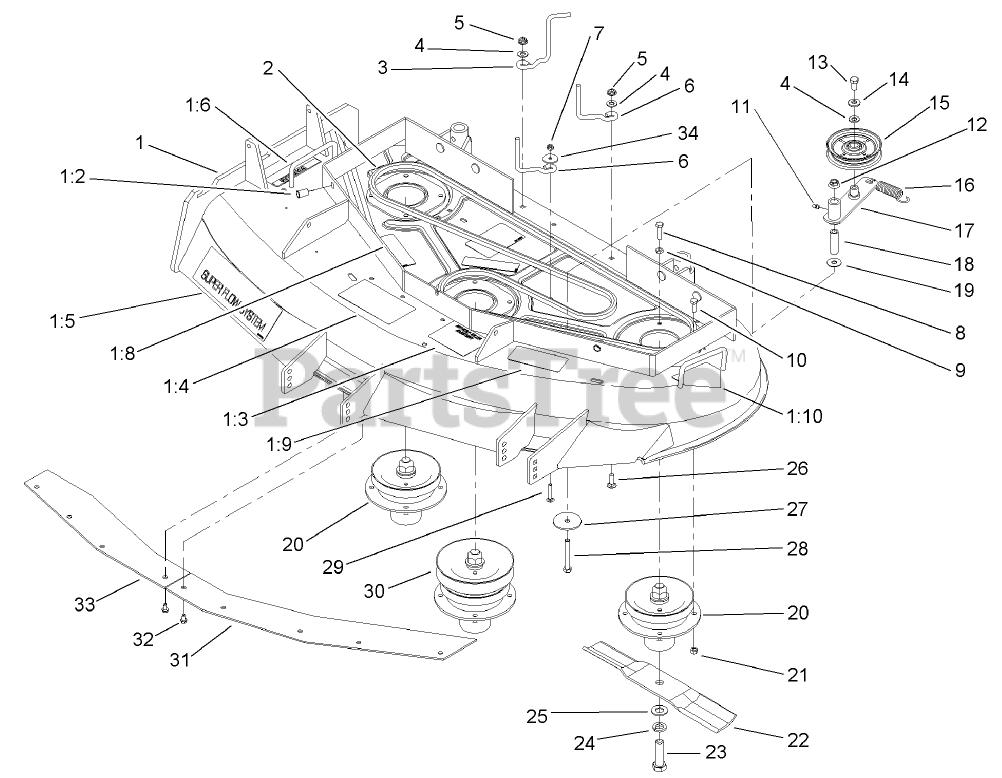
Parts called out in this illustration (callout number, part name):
1	Deck ASM
1:2	INSERT-NUT
1:3	DECAL-ANTI SCALP
1:4	DECAL-DANGER, THROWN OBJECT
1:6	DECAL-WARNING
1:7	DECAL-ROUTING, BELT
1:8	DECAL-DANGER
1:9	DECAL-TORQUE
1:10	DECAL-DANGER
2	V-BELT
3	Guide-Belt
4	WASHER-FLAT
5	NUT-HF
6	ROD-BELT
7	NUT-LOCK, HHF
8	SCREW-HH
9	NUT-JAM
10	SCREW-HH
11	FITTING-GREASE
12	NUT-HF
13	SCREW-HH
14	WASHER-BELLEVILLE
15	PULLEY-IDLER
16	Spring-Extension
17	IDLER ARM ASM
18	TUBE-IDLER
19	WASHER
20	Spindle Housing ASM
21	NUT-LOCK, CONE
22	Blade
23	SCREW-BLADE
24	WASHER-LOCK
25	WASHER-FLAT
26	BOLT-CARR
27	WASHER-END
28	SCREW-HH
29	SCREW-CARR
30	Spindle Housing ASM
31	PLATE-BLOWOUT, LH
32	SCREW
33	PLATE-BLOWOUT, RH
34	Washer-Retainer, Pulley
